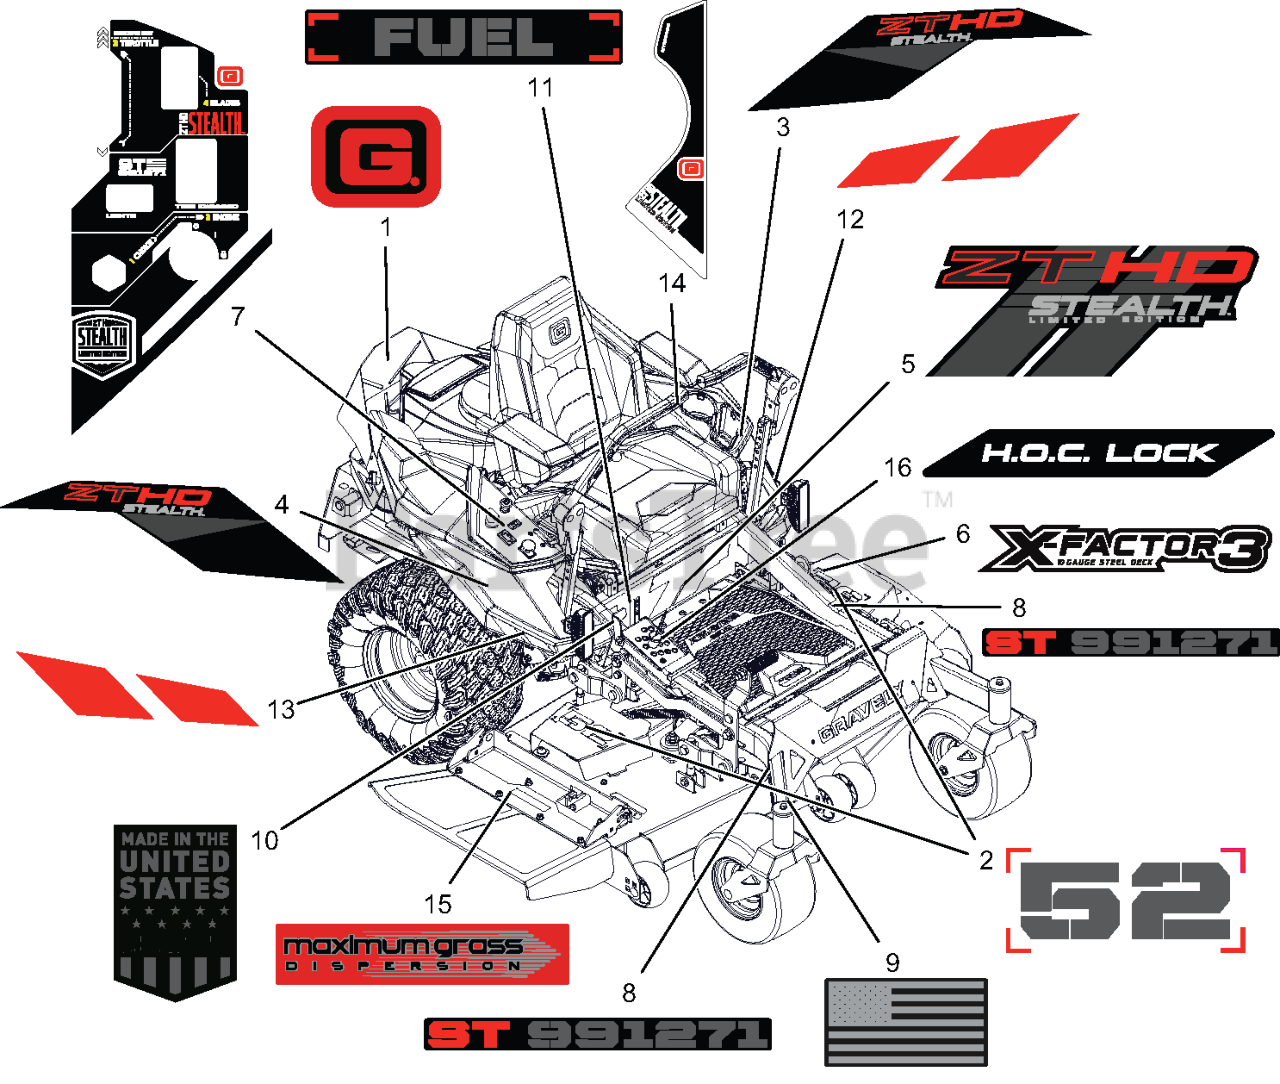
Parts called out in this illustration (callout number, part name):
1	DECAL- GRAVLEY
2	DECAL- HD STEALTH 52 DECK
3	DECAL- HD STEALTH FENDER L
4	DECAL- HD STEALTH FENDER R
5	DECAL- HD STEALTH KICKPLATE
6	DECAL- HD STEALTH X-FACTOR3
7	DECAL- CONTROLS HD STEALTH
8	DECAL- HD STEALTH ST 991271
9	DECAL- HD STEALTH USA FLAG
10	DECAL- HD STEALTH MADE IN USA
11	DECAL- HD STEALTH FUEL
12	DECAL- HD STEALTH STRIPES L
13	DECAL- HD STEALTH STRIPES R
14	DECAL- CUP HOLDER HD STEALTH
15	DECAL, DECK - MAX GRASS
16	DECAL- HD STEALTH HOC LOCK
